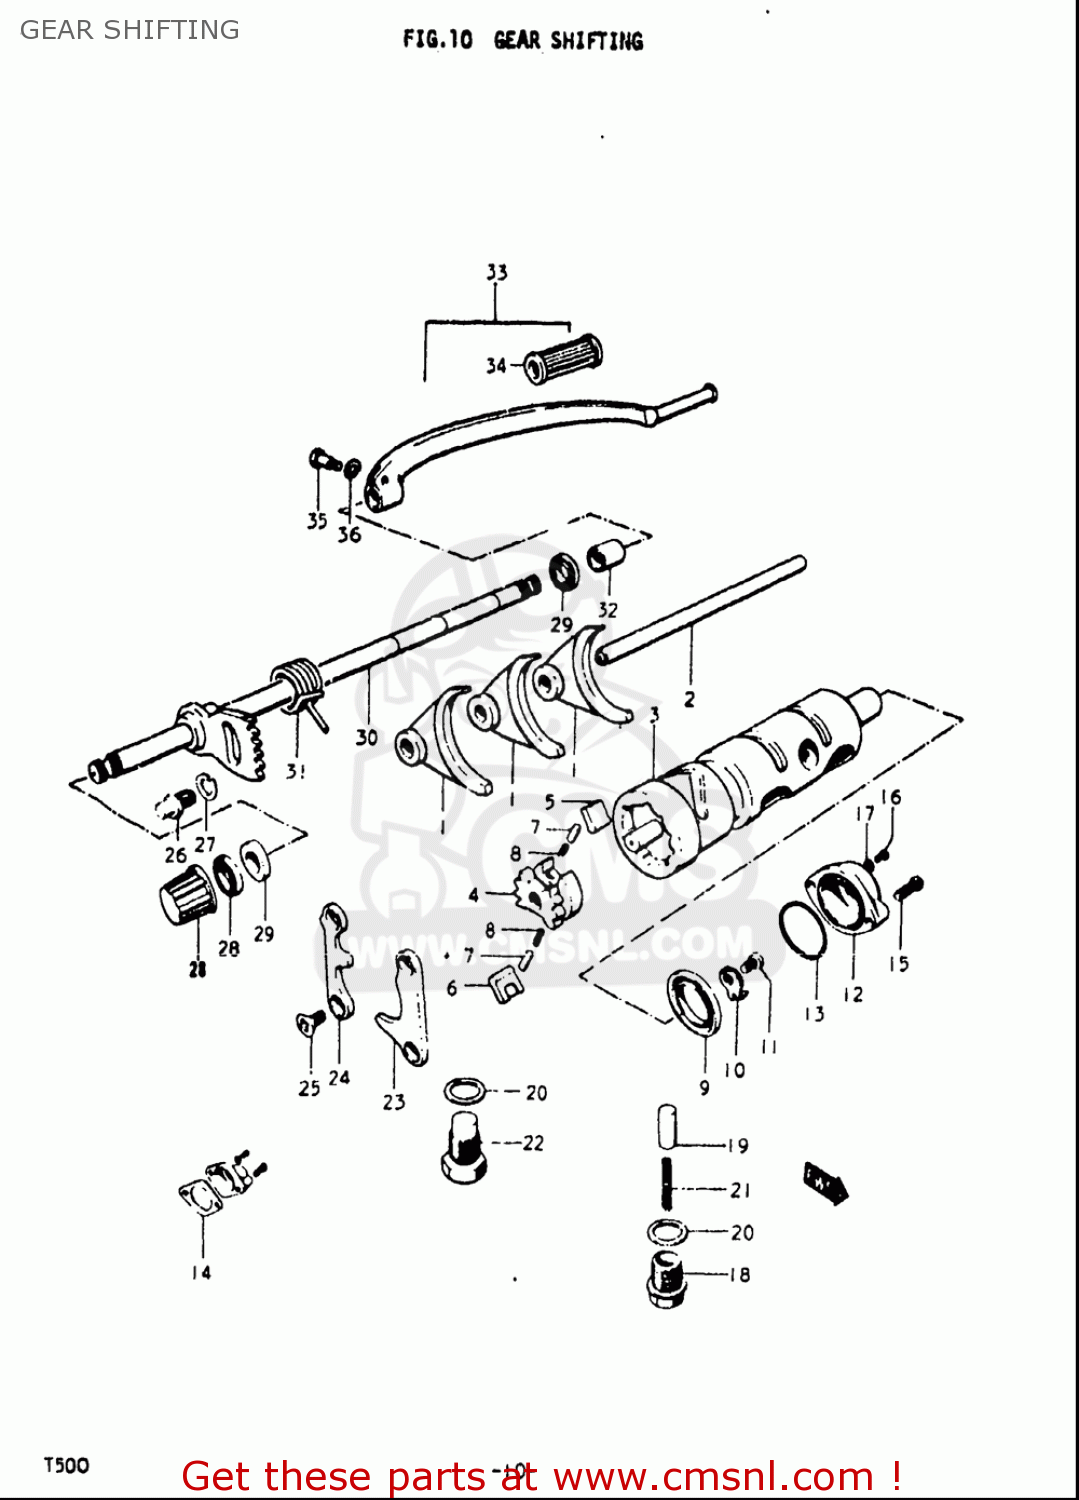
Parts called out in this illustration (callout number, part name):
4	GEAR,GEAR SHIFT CAM DRIVEN
5	PAWL,GEAR SHIFT NO.1
6	PAWL,GEAR SHIFT NO.2
7	PIN(5X8)
8	SPRING
9	SEAL,OIL(16X30X8)
10	CONTACT,GEAR SHIFT SWITCH
11	SCREW
12	BODY,GEAR SHIFT SWITCH
13	O RING(D:1.9,ID:27.7)
14	GASKET (MCA)
15	SCREW
16	SCREW
17	WASHER
18	HOUSING,GEAR SHIFT CAM STOPPER
19	STOPPER,REVERSE CAM
20	GASKET(14X19.2X2) (NAS)
21	SPRING
22	BOLT
23	LIFTER,GEAR SHIFT PAWL
24	GUIDE,GEAR SHIFT
25	SCREW
26	STOPPER,GEAR SHIFT ARM
27	WASHER,LOCK
28	SEAL,OIL (12X22X9)
29	CUSHION
31	SPRING
33	LEVER ASSEMBLY,GEAR SHIFTING
34	RUBBER,GEAR SHIFT PEDAL
35	BOLT
36	WASHER,LOCK
